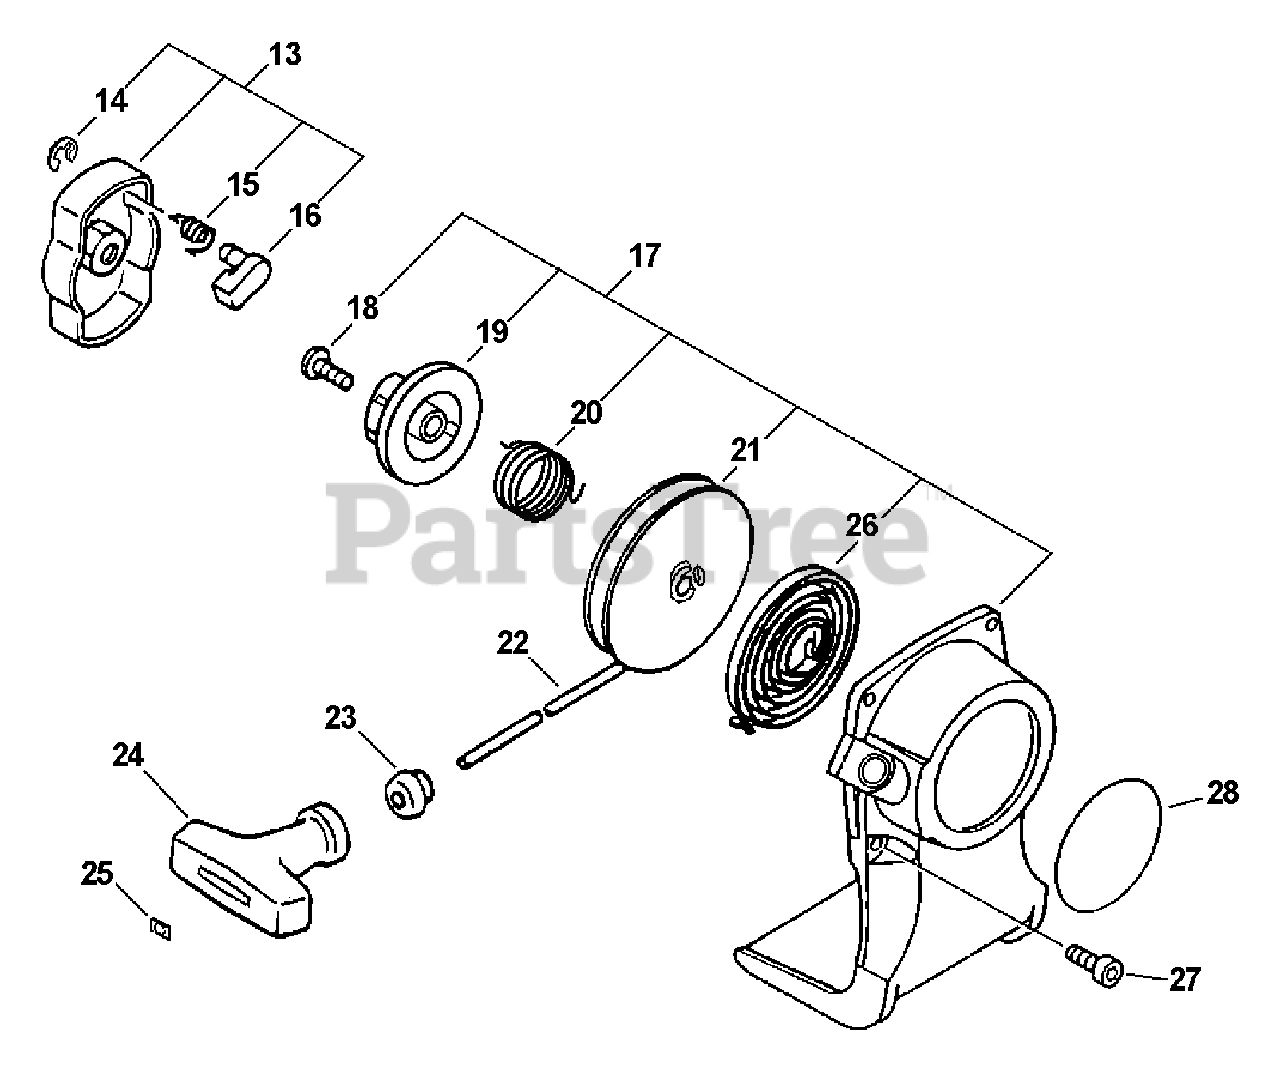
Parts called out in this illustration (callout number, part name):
13	PAWL ASSY, STARTER
14	E-RING 4
15	SPRING, RETURN
16	PAWL, STARTER
17	STARTER, RECOIL
18	SCREW
19	PLATE, CAM (NLA SEE PB 15-06)
20	SPRING, TORSION
21	REEL, ROPE
22	ROPE, STARTER 3×700
23	GUIDE, ROPE
24	GRIP, STARTER
25	RETAINER, ROPE
26	SPRING, RECOIL
27	BOLT 4×16
28	LABEL - ECHO -- I-30
